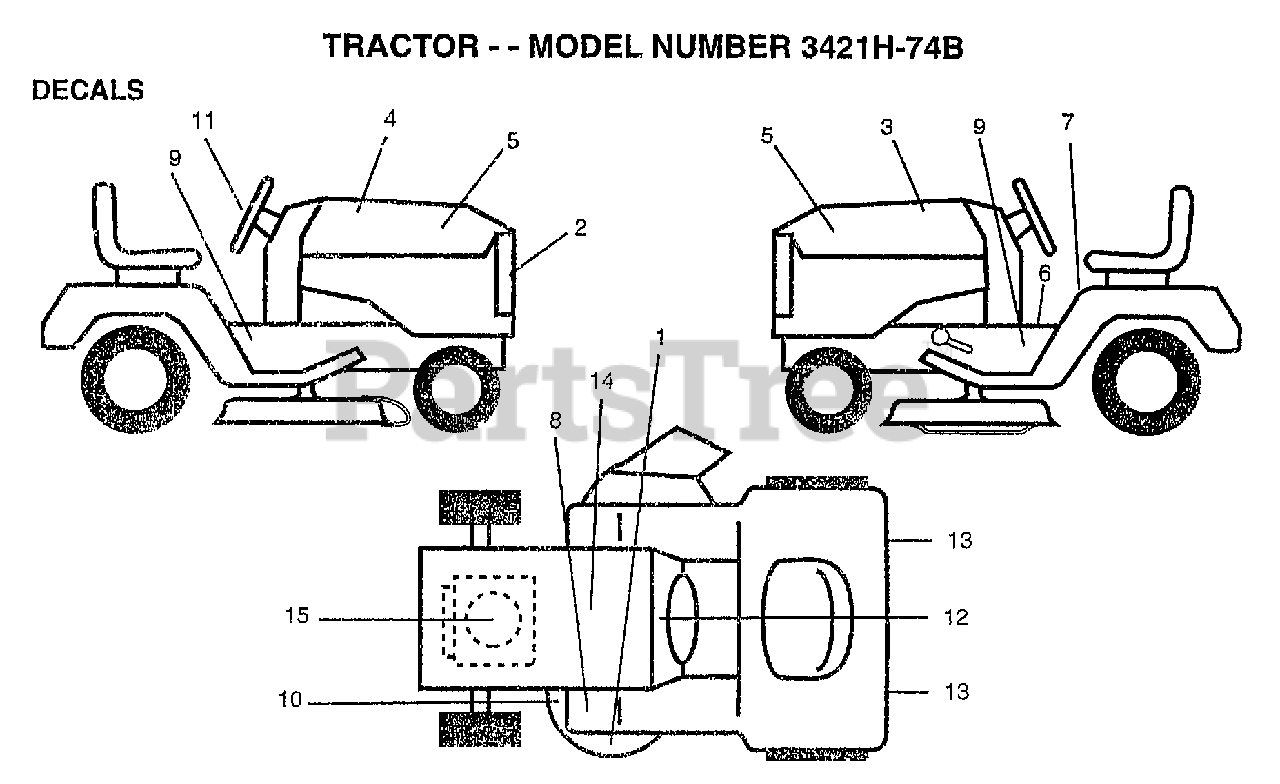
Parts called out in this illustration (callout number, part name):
2	GRILL DECAL
3	"DECAL.HOOD,LH"
4	"DECAL HOOD,RH"
5	NAMEPLATE LOGO
6	DECAL BRAK PARK
7	"DECAL DANGER,FEND"
9	DECAL-CHASSIS
10	DECAL
12	"DECAL-INST,OPER"
13	REFLECTOR-TAIL YT
14	DECAL.BATRY.3-3908
15	DECAL, HP ENGINE
